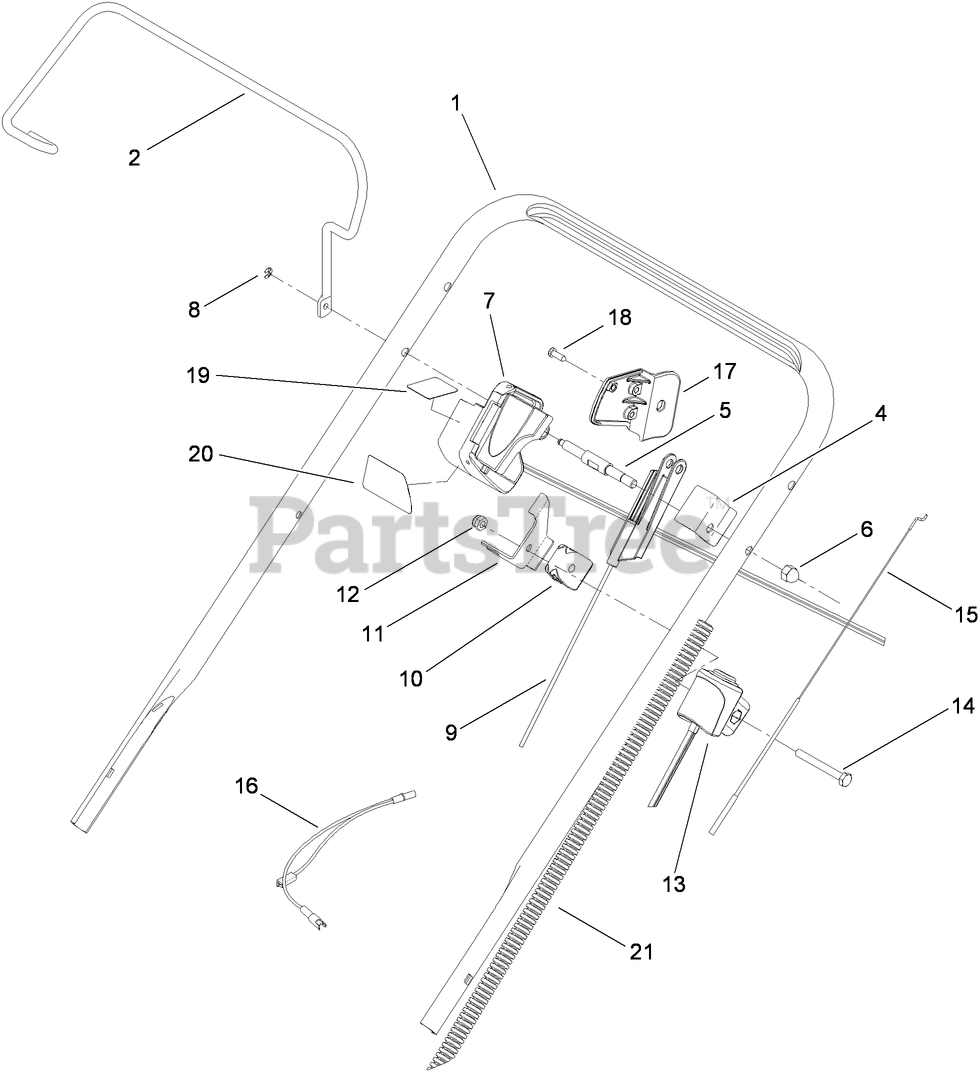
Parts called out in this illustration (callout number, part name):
1	HANDLE-UPPER
2	BAIL-BRAKE
4	BRACKET-HANDLE, STOP
5	PIN-PIVOT
6	NUT-ACORN
7	SAFETY SWITCH ASM
8	RING-RETAINING
9	CABLE-BRAKE
10	ANCHOR-CABLE, UPPER
11	BRACKET-STOP
12	NUT-LOCK, NI
13	SWITCH HOUSING ASM
14	SCREW-HH
15	CABLE-TRACTION
16	HARNESS-WIRE
17	COVER-SWITCH
18	SCREW-PPH
19	DECAL-CONTROL, BLADE
20	DECAL-BRAKE CONTROL, BLADE
21	TUBE-LOOM, SPLIT
